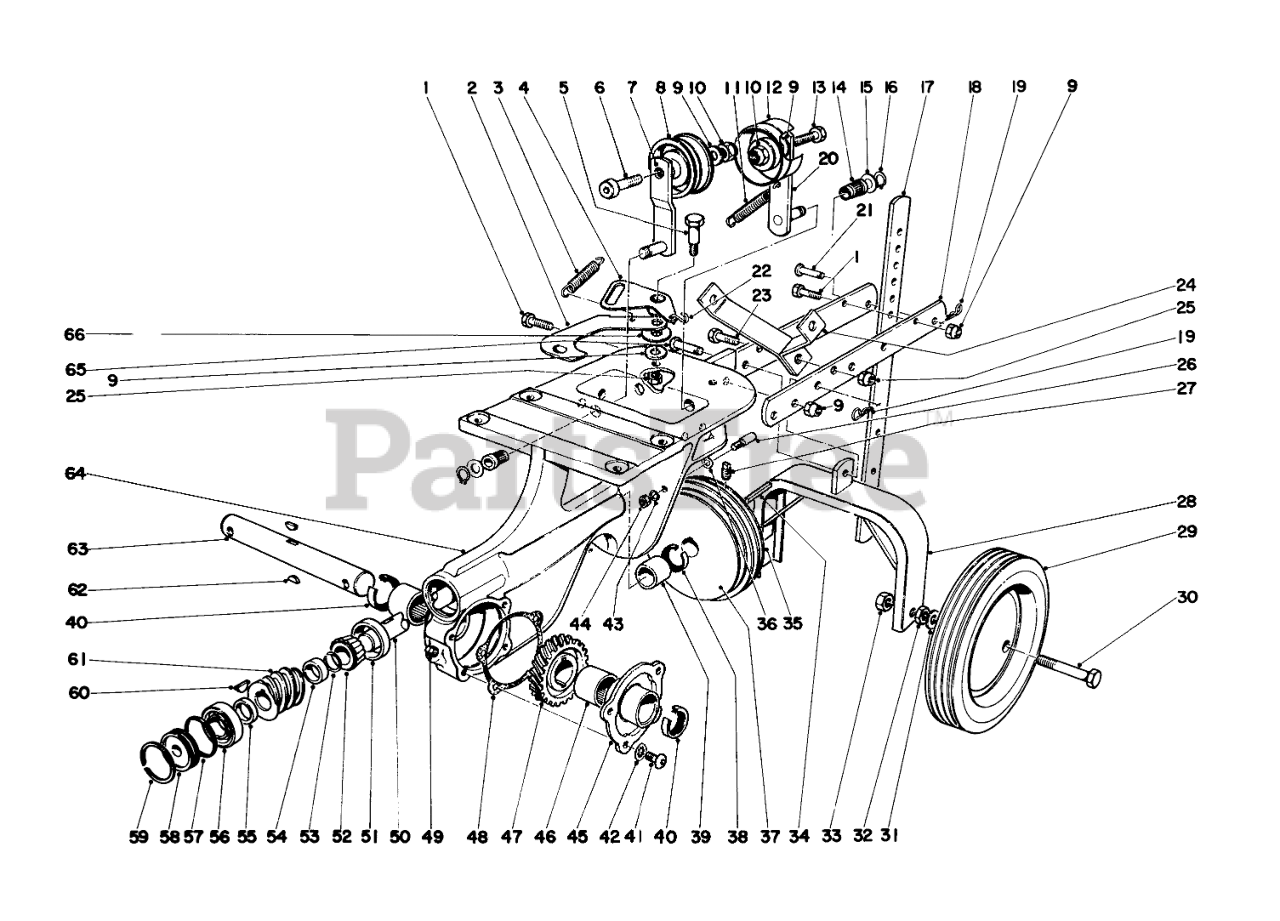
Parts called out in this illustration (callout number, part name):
1	SCREW-HH
2	Rev. Link
3	Spring
4	Bellcrank
5	SCREW-SHOULDER, HH
6	Capscrew
7	IdlerArm
8	PULLEY IDLER
9	WASHER-FLAT
10	NUT-LOCK, CONE
11	Spring
12	IDLER PULLEY
13	SCREW-HH
14	IDLER BRG
15	WASHER-PLAIN
16	RING-RETAINING, EXT
17	DEPTH GAGE
18	Drawbar
19	PIN-COTTER, HAIR
20	Idler
21	Pin
22	S Hook
23	SCREW-HH
24	Handle Support
25	NUT-LOCK, CONE
26	Belt Guide
27	SCREW-SET, HSH
28	Wheel Bracket
29	Wheel
30	Axle
31	WASHER-FLAT
32	NUT-JAM
33	1/2-13 CONELOCK NUT
34	KEY-SQUARE
35	Pulley
36	WASHER-FLAT
37	Pulley
38	SEAL-OIL
39	BUSHING
40	SEAL-OIL
41	SCREW-HSBH
42	WASHER-LOCK
43	WASHER-LOCK/EXT
44	NUT-JAM
45	Cover
46	Bearing
47	WORM WHEEL
48	GASKET
49	PLUG-PIPE, SQH
50	WORM SHAFT
51	1.750 ROLLER BRG CUP
52	3/4 ROLLER BRG CONE
53	RETAINER RING
54	WORM SHF REAR SPACER
55	SPACER
56	.750 BALL BEARING
57	O-RING
59	INTRNL RETAINING RING
60	KEY-WOODRUFF
61	WORM GEAR
62	KEY-WOODRUFF
63	WORM WHEEL SHAFT
64	Chassis
65	Pin
66	WASHER-FLAT
